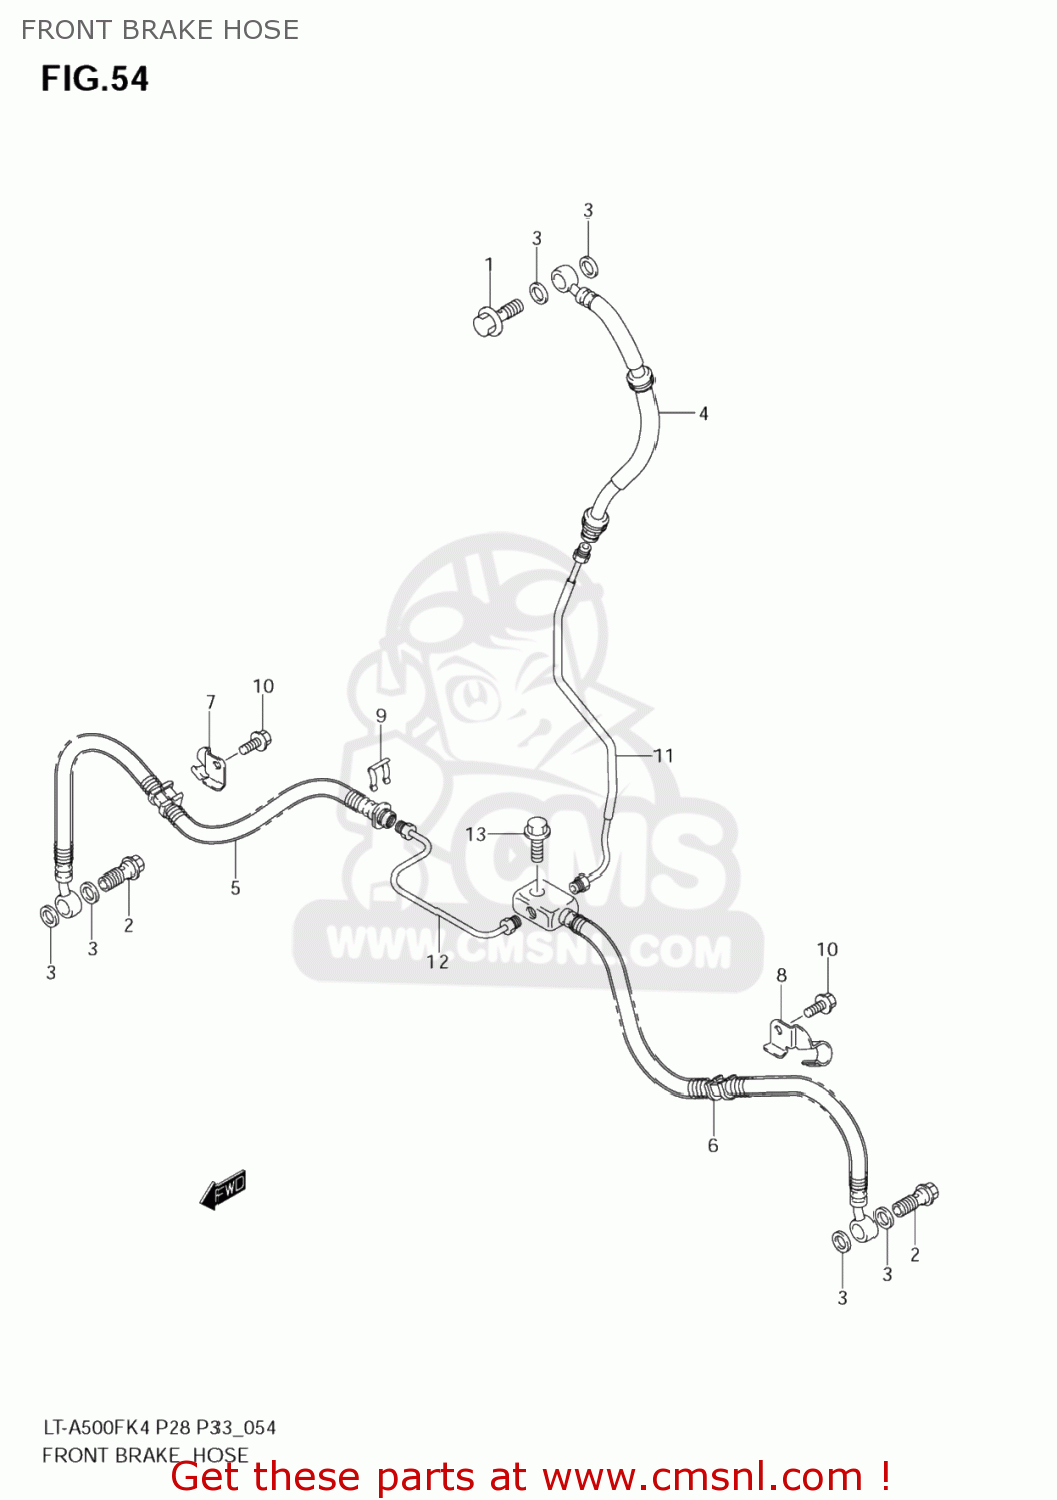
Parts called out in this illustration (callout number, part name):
1	BOLT UNION
2	BOLT UNION
3	WASHER(10X15X1.5)
4	HOSE,FR BRAKE NO.1
5	HOSE,FR BRAKE NO.2,R
6	HOSE,FR BRAKE NO.2,L
7	CLAMP,FR BRAKE HOSE NO.2,R
8	CLAMP,FR BRAKE HOSE NO.2,L
9	E-RING
10	BOLT
11	PIPE,FR BRAKE,R
12	PIPE,FR BRAKE NO.2
13	BOLT
